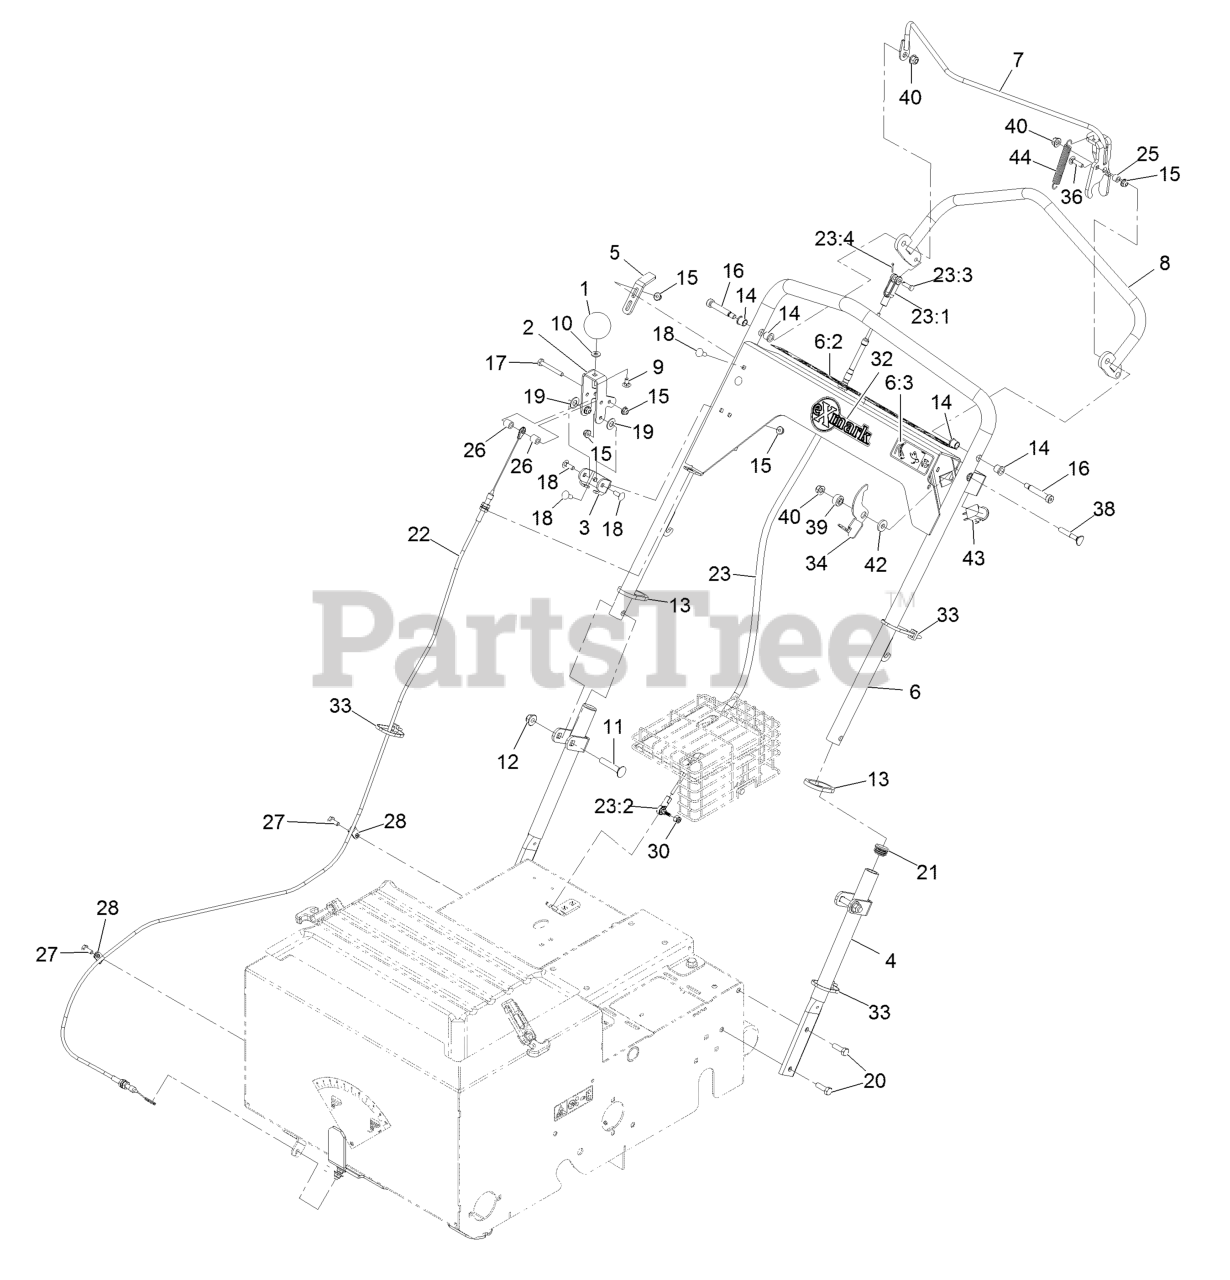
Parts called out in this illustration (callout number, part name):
1	Knob-Rate, Flow
2	Lever-Adjust, Flow
3	Bracket-Adjust, Flow
4	Handle-Lower
5	Bracket-Adjust, Drive
6:2	Decal-Control Panel, Seeder
6:3	Decal-Safety Latch
7	Bail-Clutch
8	Handle-Drive
9	Bolt-Carriage 1/4-20 X 1/2
10	Washer-1/4 SAE
11	Bolt-Carriage 3/8-16 X 2
12	Nut-Nyloc 3/8-16 Flg
13	Ring-Handle Lock
14	Bearing
15	Nut-Nyloc 1/4-20 Flg
16	Screw-Shoulder
17	Screw-HH 1/4-20 X 2
18	Bolt-Carriage 1/4-20 X 3/4
19	Washer-Plain
20	Screw-HH 5/16-18 X 1
22	Cable-Flow, Seed
23	Cable-Push Pull
23:2	Ball Joint
23:3	Pin-Clevis
23:4	Pin-Cotter 3/32 X 1/2
27	Screw-HH 1/4-20 X 5/8
28	Clamp-R
30	Nut-Nyloc 1/4-28
32	Decal-Exmark Logo
33	Tie-Cable
34	Latch-Bail
36	Bolt-Carriage 1/4-20 X 1
38	Bolt-Carriage 5/16-18 X 2
39	Bushing-Stepped
40	Nut-Nyloc 5/16-18 Flg
42	Washer-Flat
